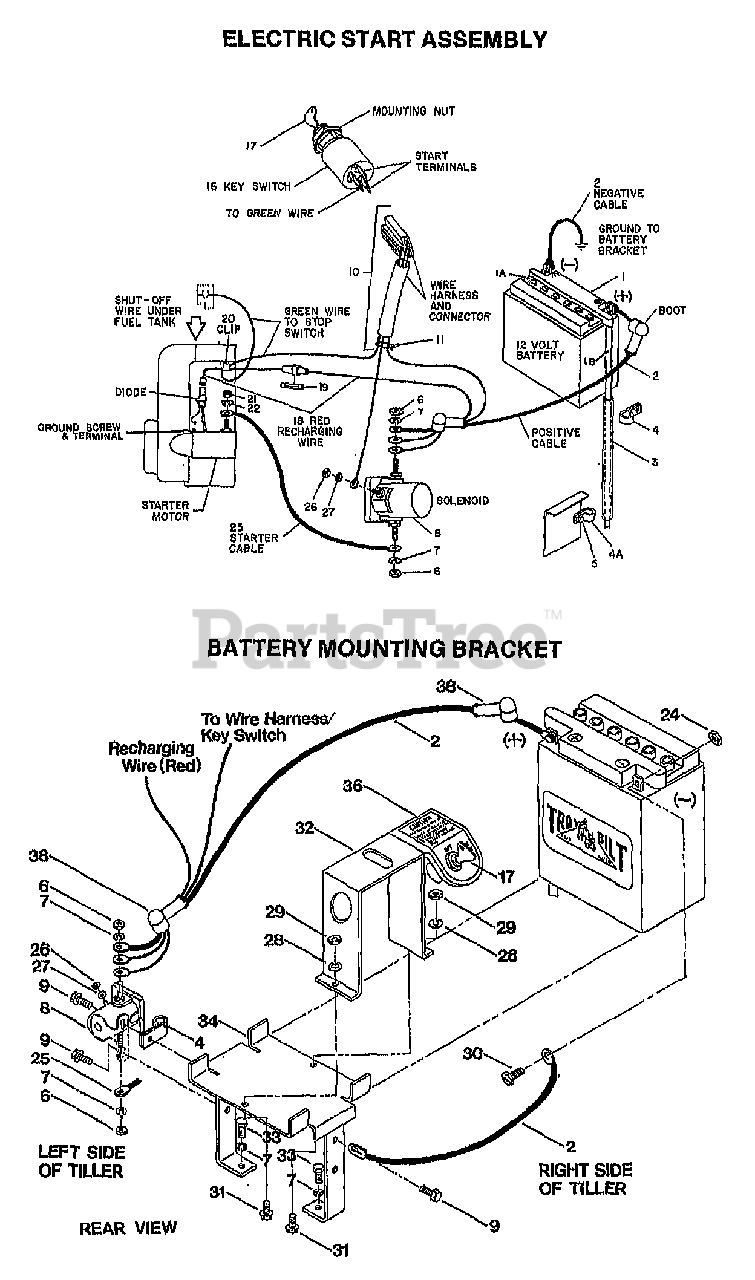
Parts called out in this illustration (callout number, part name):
1	BATTERY (INCL. HARDWARE TO CONNECT BATTERY CABLE TERMINALS TO BATTERY POSTS)
1A	CAP-YELLOW
1A	CAP-BATTERY WHITE (PONY)
1B	TUBE-VENT BATTERY/HSE
2	CABLE-BATTERY (REPLACES #9223)
3	TUBING-RUBBER
4	CLAMP (SMALL)
4A	CLAMP (LARGE)
5	SCR-HHC 5/16-18X.75 GR 5
6	NUT-HEX 5/16-24
7	WASHER-LK .312
8	KIT-SOL W/HDW
9	SCR-HWH 1/4-20 X .5 STH
10	ASSM-HARNESS (AVIL. AS COMPLETE UNIT ONLY)
11	TIE-TWIST LOCK
16	KEYSWITCH W/KEYS
17	KEYS(1 PAIR) FOR SWITCH
18	WIRE-RECHARGE 5&7 BRIGGS
19	FUSE-3 AMPERES
20	CLIP-SPECIAL
21	NUT-HEX, #10-24 (NOT AVAIL. FROM GARDEN WAY)
22	LOCKWASHER-#10 (NOT AVAIL. FROM GARDEN WAY)
24	NUT (NOT AVAIL. FROM GARDEN WAY)
25	CABLE-STARTER
26	NUT-HH M10-32X.125
27	WASHER-EXTERNAL TOOTH 1
28	WASHER-LK .25
29	NUT-HEX 1/4-20
30	BOLT (NOT AVAIL. FROM GARDEN WAY)
31	SCR-CARR 1/4-20X1.25
32	PLTE-KEYSWITCH W/DEC-PONY 3 (INCL. #20418)
33	SCR-HH 5/16-18X1.0 G5
34	BRKT-BATTERY PNT
36	DECAL-KEYSWITCH TILLER
